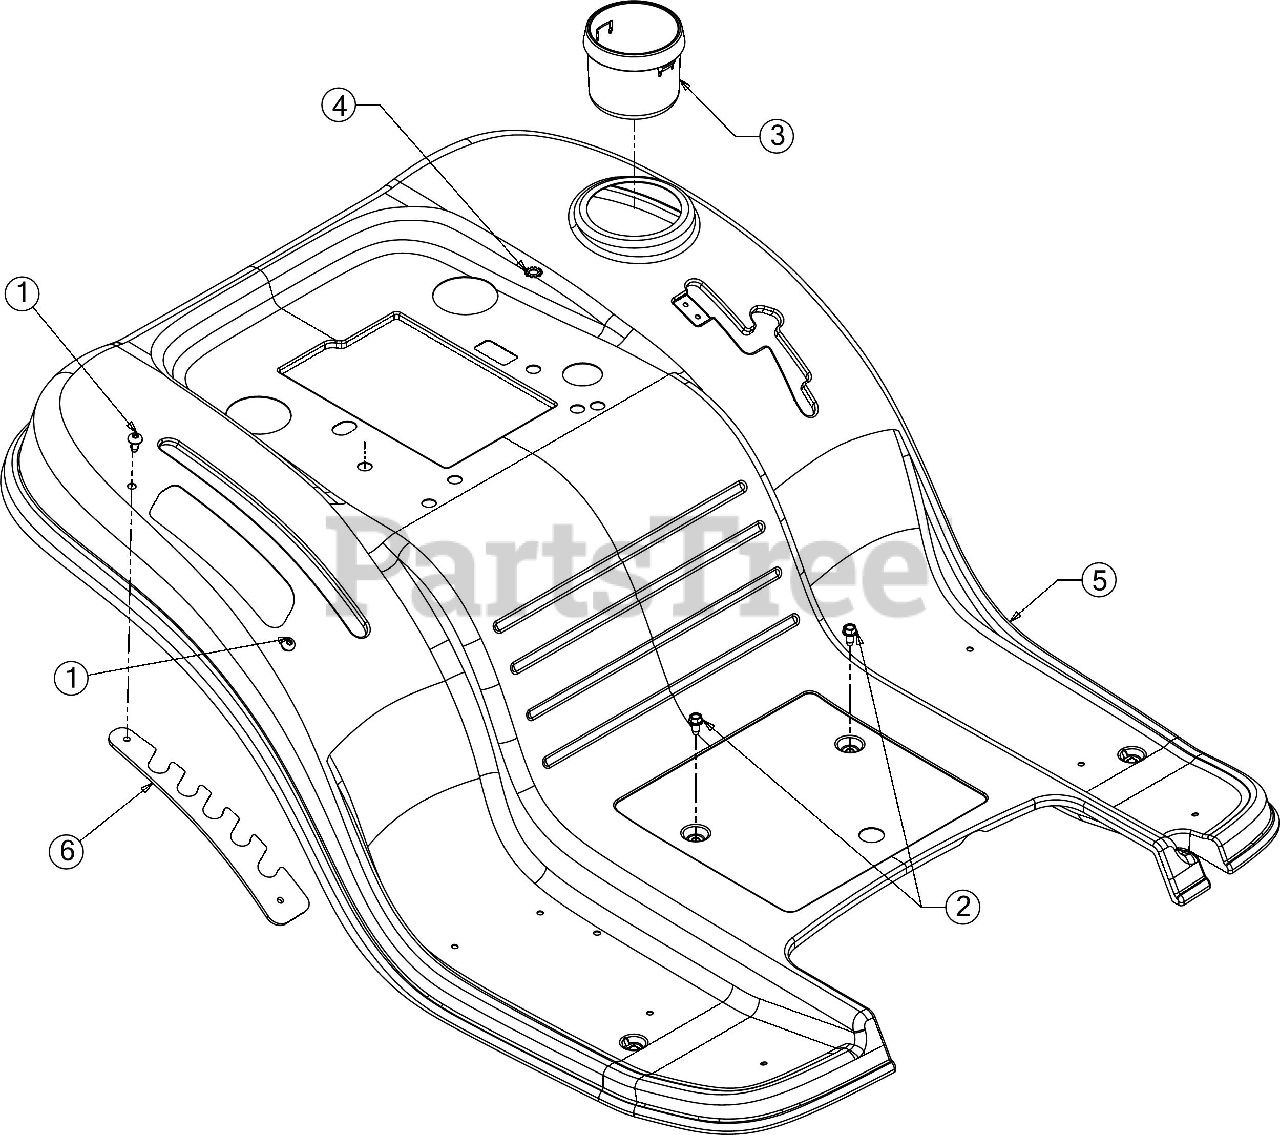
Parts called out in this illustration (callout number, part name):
1	SCREW 1/4-20 x .5
2	SCREW 1/4-20 X.500
5	FENDER
6	LIFT ADJUSTMENT BRACKET
